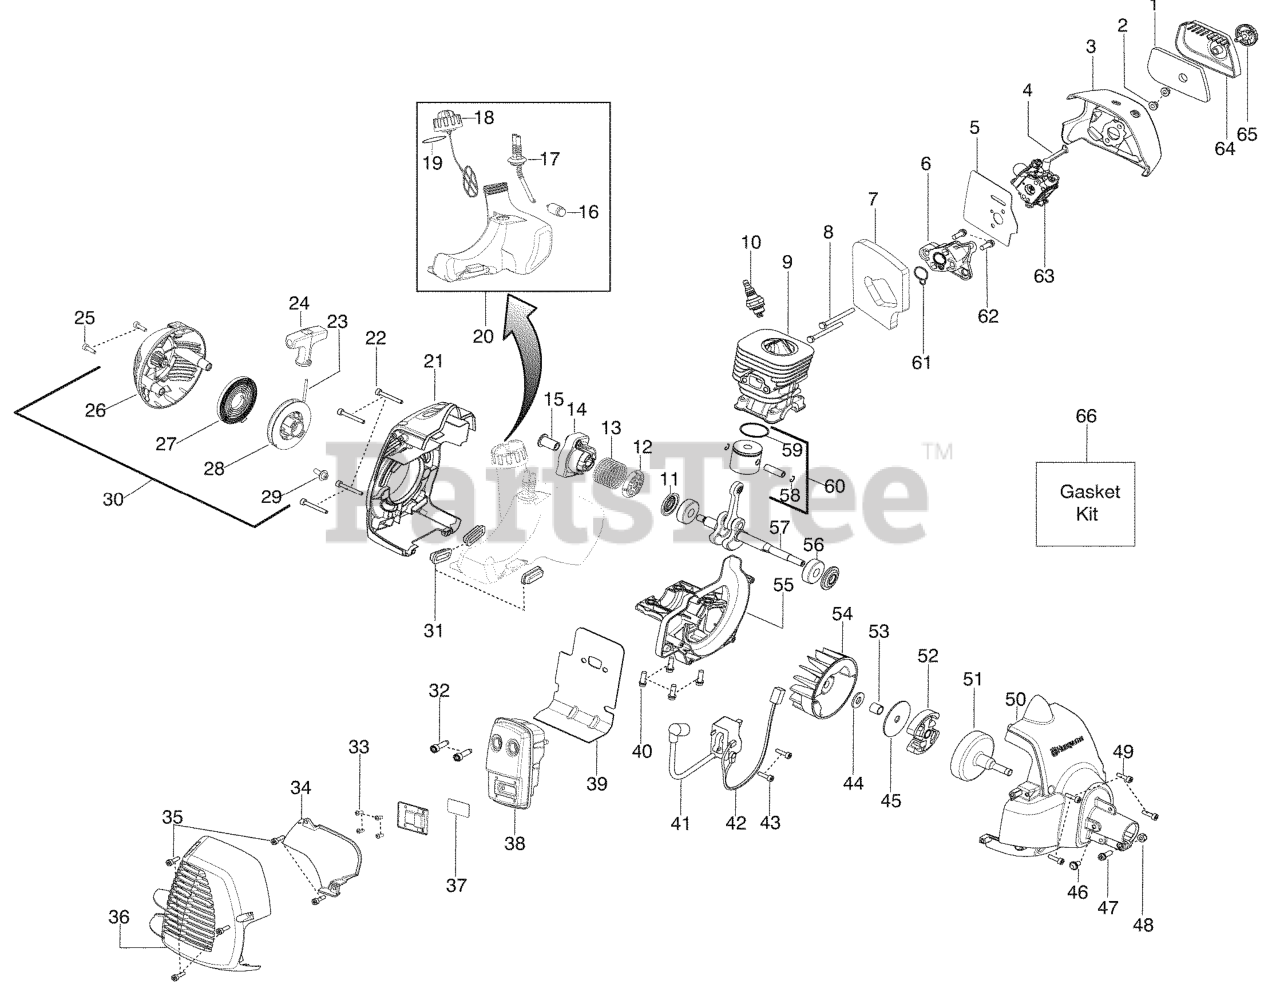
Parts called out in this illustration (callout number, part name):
2	Nut-Carb. Screw
3	Air Box
4	Lever - Choke
5	Kit-Carb. Gasket
6	Adaptor-Carb.
7	Kit-Gasket
9	Cylinder
10	Plug-Spark (RCJ-6Y)
11	Kit-Crankshaft seal
12	Washer-Starter
13	Spring-Starter Cup
14	Assy-Starter Cup
15	Coupling-Starter
16	Assy-Fuel Filter
17	Kit-Fuel Line
18	Assy-Cap w/ret.
19	Kit Gasket O-ring - Fuel Cap
20	Assy-Fuel Tank
21	Shroud-Rear
24	Handle-Starter
25	Screw
26	Starter Hsg. w/eyelet
27	Kit-Starter Spring
28	Kit-Starter Pulley
30	Assy-Starter Hsg.
31	Isolator-Tank
32	Bolt-Muffler
34	Shield-Heat
36	Guard-Muffler
37	Kit-Spark Arrestor
38	Assy-Muffler
39	Kit-Gasket-Paper met.
41	Module
42	Assy-Leadwire
45	Washer-Clutch
50	Assy-Fan Housing
51	Assy-Clutch Drum
52	Kit-Clutch Assy.
55	Crankcase
57	Kit-Crankshaft
58	Retainer-Piston Pin
59	Ring-Piston
60	Kit-Piston
61	Kit-Gasket
63	Kit-Carb.
64	Cover-Air Box
66	Kit-Gasket
